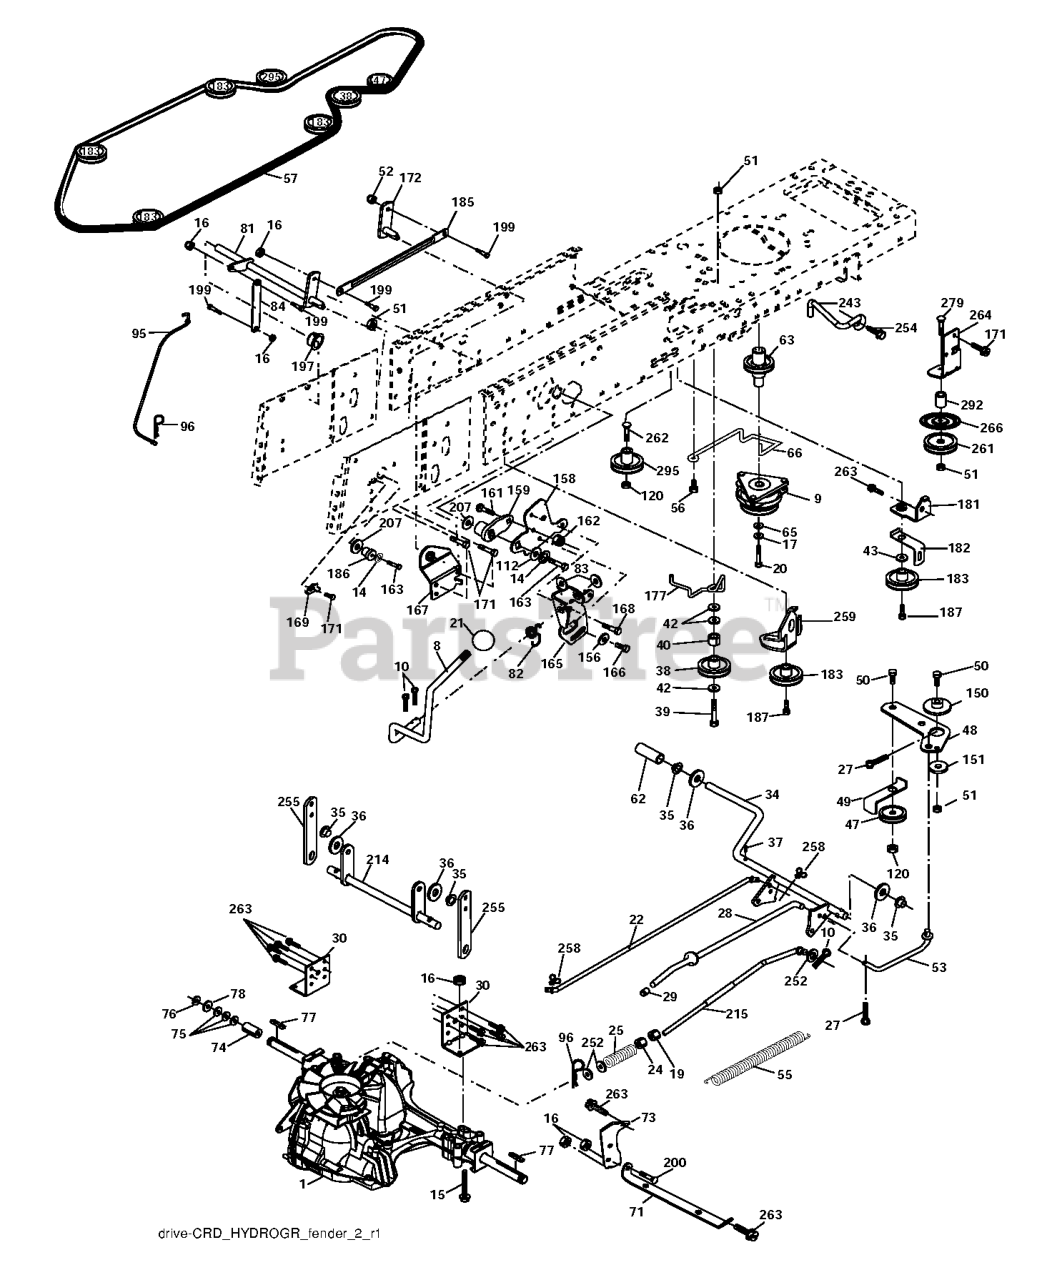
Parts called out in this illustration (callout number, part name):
8	ROD SHIFT FENDER ADJUST LT
9	CLUTCH.ELECTRIC.OGURA.EURO.
10	PIN COTTER
14	LOCKWASHER
15	BOLT HEX 5/16-18 GR 5
16	NUT.71038.31-18.HEX.NYLOCK
19	NUT
20	BOLT HEX 7/16-20X4-1/4"
21	KNOB.DUCKHEAD.1/2
22	ROD
24	NUT
25	SPRING BRAKE ROD
27	COTTER PIN
28	ROD, PARKING BRAKE
29	CAP
30	BRKT, TRNSXLE MNT 20"
34	SHAFT, FOOT PEDAL
35	BEARING.NYLON
36	WASHER LT
37	DRIVE PIN
38	PULLEY.FLAT
42	WASHER
43	WASHER T
47	IDLER PULLEY
48	BELLCRANK, CLUTCH
49	RETAIN BELT
50	BOLT.3/8-16X1.50
52	LOCKNUT
53	LINK.CLUTCH.7.66.2005
55	SPRING, RETURN LT
56	SCREW.3/8-16
57	V-BELT 113"
62	PEDAL COVER T
63	PULLEY.ENGINE.CVX.LT
65	LOCKWASHER
66	KEEPER BELT ENGINE
71	STRAP TORQUE LH HYDRO
73	STRAP TORQUE RH HYDRO
74	SPACER AXLE
77	SQUARE KEY
81	ASM.CROSS.SHAFT.REAR.CRD.0510
82	SHIFT SPRING
83	WASHER
84	LINK.PNT.TRANSAXLE.0510.CRD
95	LINK
96	RETAINER M
112	WASHER LT
120	NUT LOCK FLG 3/8-16 UNC
150	BUSHING.BELLCRANK.GRD.DR
151	WASHER 12/32X2X10GA
156	WASHER.SRRTD.5/16
158	BRACKET
159	RB HUB.SHIFT
161	BOLT
162	NUT.CROWNLOCK.1/4
163	BOLT
165	RP BRACKET
166	CAPSCREW.HXHD.FLG.5/16-18X.625
167	BRACKET.SUPT.SHIFT.CRD
168	BOLT.SHOULDER.5/16-18X
169	PLATE.FASTENING.CROSS.SHAFT
171	SCREW LT
172	LINK
181	BRACKET
182	BELT GUIDE
183	PULLEY.V-IDLER.GRND.DR
185	LINK
186	HUB.TAPERED.ROUND.CRD
187	BOLT.5/16-18X1.25
197	NYLINER SNAP 5/8" ID
199	BOLT SHOULDER 5/16-18 UNC
200	BOLT
207	WASHER NYL
214	LEVER
215	ROD
243	BRACKET, ANTI-ROTATION
252	WASHER
254	SCREW 3/8-16X1
255	SHAFT
258	CLIP RETAINER
259	BRACKET
261	FLAT IDLER PULLEY
263	SCREW, 3/8-16X3/4
266	PROTECTOR
279	BOLT
292	SPACER
295	PULLEY IDLER COMPOSITE
